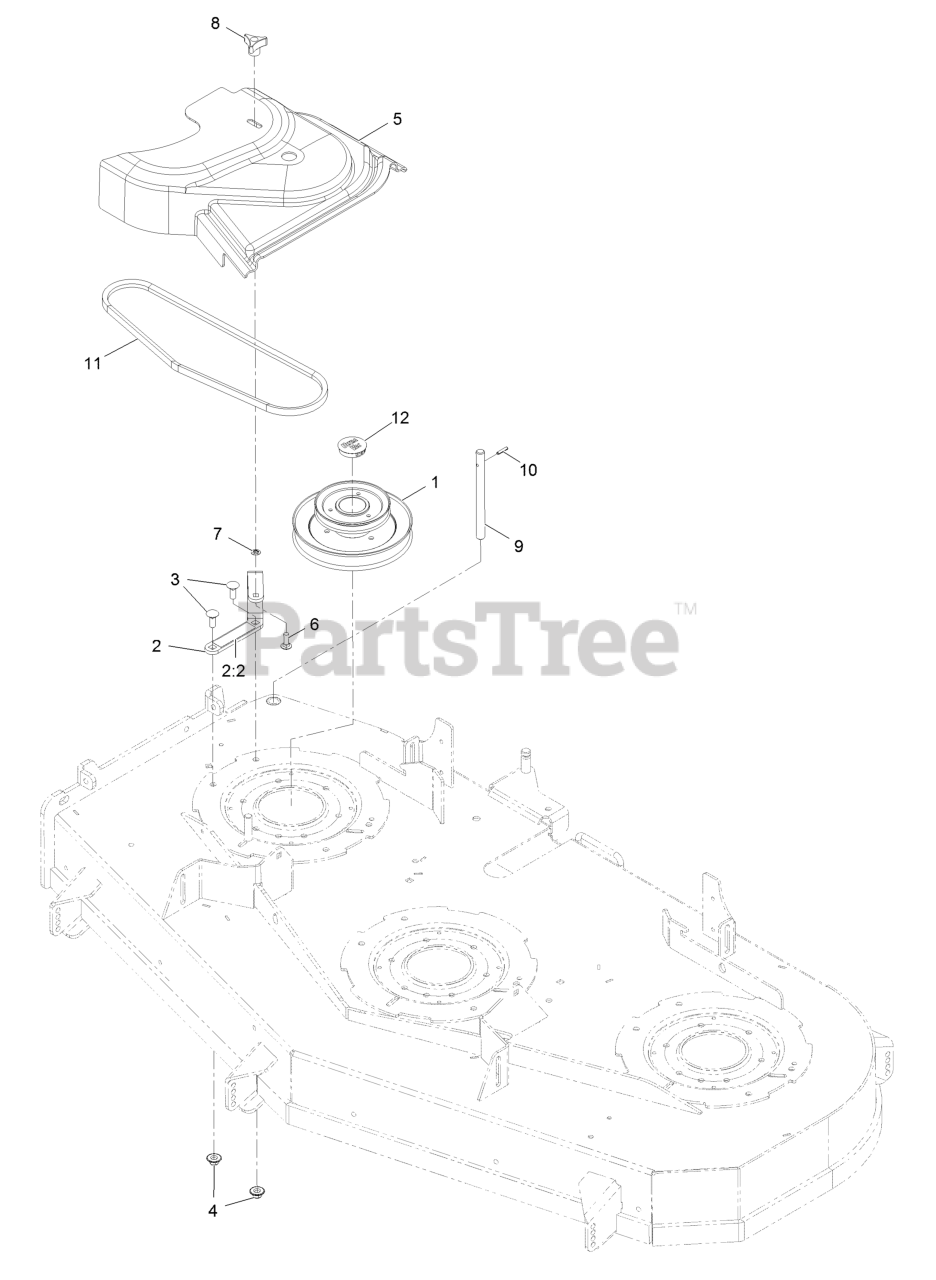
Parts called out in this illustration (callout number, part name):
1	JACKSHAFT,UV DRIVE 604 SPLINED
2	ASM-CVR BRKT W/DECAL
2:2	DECAL-COVER, MISSING
3	BOLT-CARR
4	Nut-Nyloc 3/8-16 Flg
5	COVER-BELT UVE 60
6	BOLT-CARR
7	RING-RETAINING, BOLT
8	KNOB-3 PRONG
9	SHAFT-CATCHER, GRASS
10	PIN-ROLL
11	BELT,A 42.32
12	PLUG, BLACK NYLON 1.75
